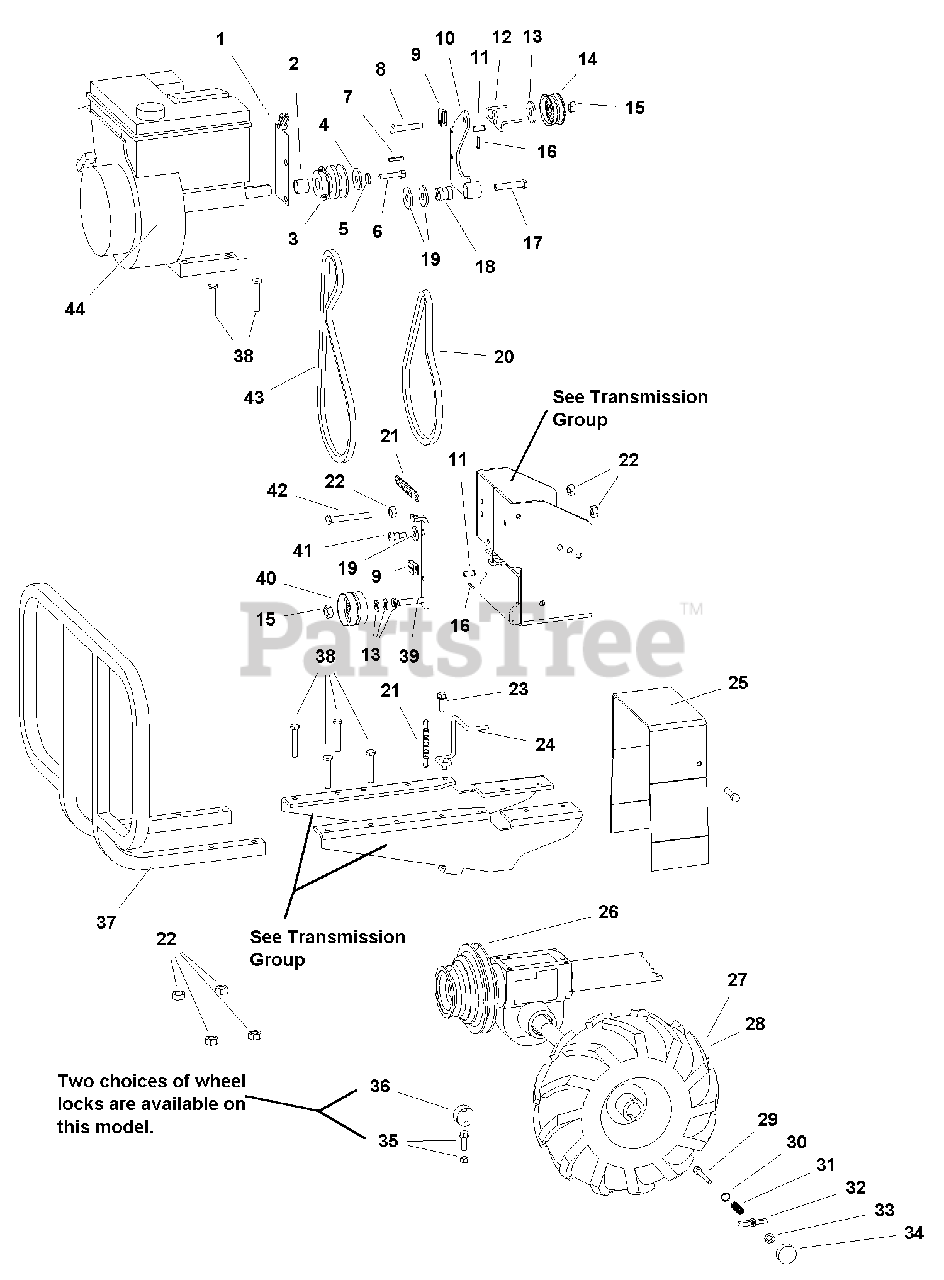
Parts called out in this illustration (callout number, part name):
1	BRACKET, Engine
2	SPACER, Engine
3	PULLEY, Engine 2 Groove
5	LOCKWASHER, Spring 5/16"
6	CAPSCREW, Hex Head 5/16"-24 x 3/4" G5
7	KEY, Parallel Plane
8	CAPSCREW, Hex Head 3/8"-24 x 2" G5
9	YOKE, Cable
11	PIN, LINK Forward/Reverse
12	GUIDE, Belt Reverse
13	WASHER, 3/8"
14	PULLEY, Idler Reverse
15	NUT, Hex 3/8"-16NC, 2B
16	PIN, Cotter
17	BOLT, Hex Head 5/16"-24 x 1-1/2"
19	WASHER, 5/16"
20	V-BELT, Forward
21	SPRING, Idler Arm
22	NUT, Hex Flange 5/16"-18 Two, Way Lock GA
23	BOLT, Hex Flange Head 5/16"-18 x 3/4"
24	GUIDE, Belt Forward
25	COVER, Belt
26	PULLEY, Transmission 2 Groove
27	WHEEL & TIRE ASSEMBLY TILLER LH
28	WHEEL & TIRE ASSEMBLY TILLER RH
29	CAPSCREW, Hex Socket Head, 1/4"-20 x 2-3/32"
30	WASHER, 1/4"
33	NUT, Hex KEPS 1/4"-20
34	KNOB, Lock Out Set of Two
35	SETSCREW, Wheel Lockout
36	CLAMP, C Wheel Lockout
37	BUMPER, Guard
38	CAPSCREW, Hex Head 5/16"-18 x 1-3/4" G5
39	ARM, Idler Forward
40	PULLEY, Forward Idler
41	SCREW, Hex Socket Shoulder 5/16"-18 x 3/8"
42	CAPSCREW, Hex Head 5/16"-18 x 3-1/2" G5
43	V-BELT, Reverse
